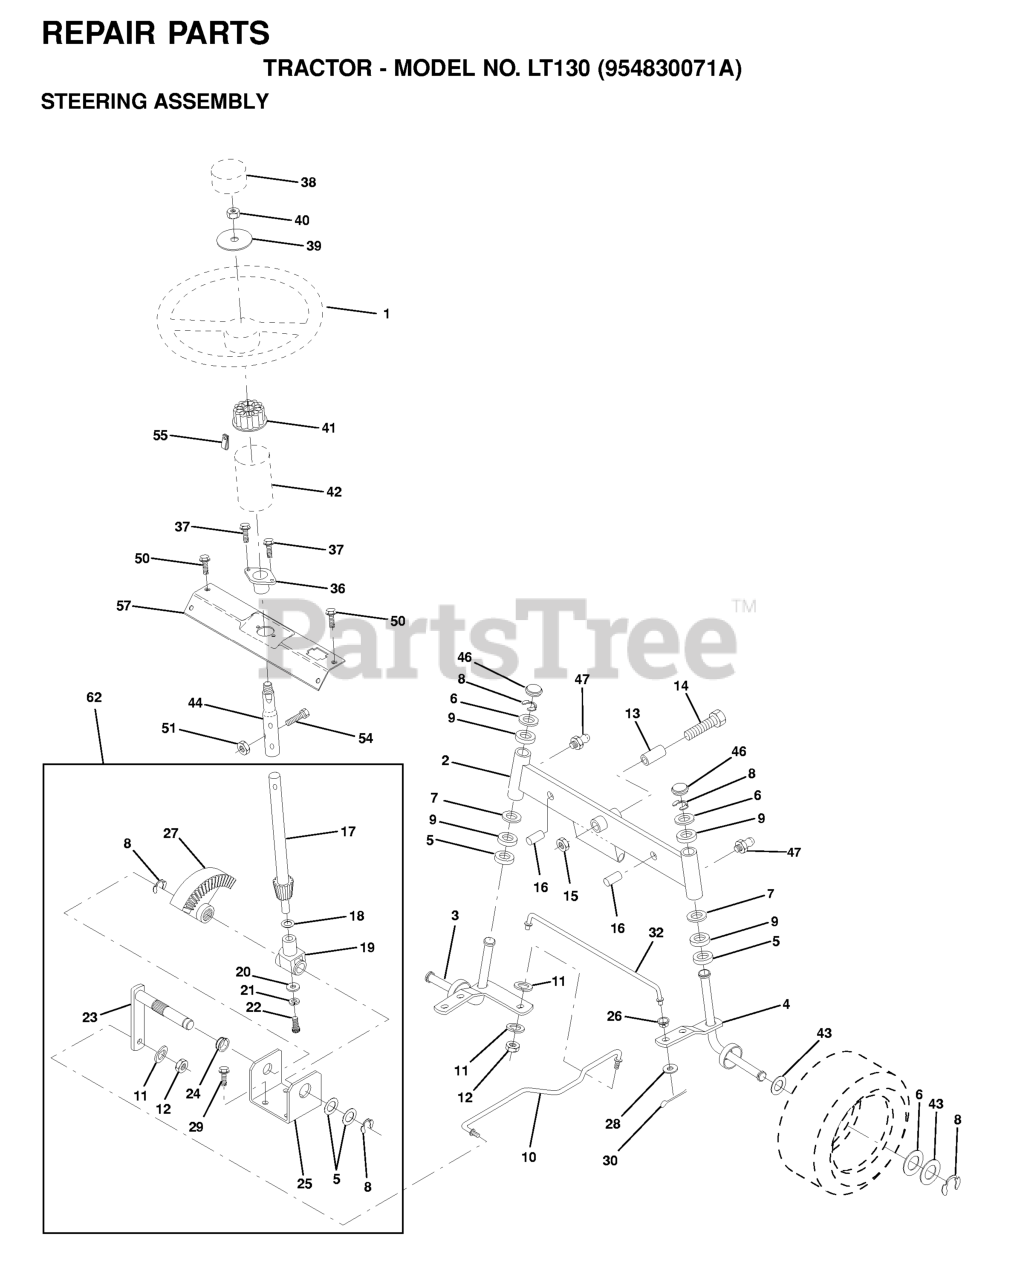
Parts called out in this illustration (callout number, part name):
1	STEERING WHEEL
3	SPINDLE LH
4	SPINDLE RH
5	THRUST WASHER
9	BRNG T
10	LINK.DRAG.SOL.BALL JT.20.064
11	WASHER, LOCK 3/8
12	NUT
13	BEARING
14	Bolt, Hex Head 5/8-11 x 3-1/2
15	NUT-LOC,FLANGE LT
17	SHAFT STEERING
18	THRUST WASHER
19	SHAFT,SUPPORT
20	WASHER
21	LOCKWASHER
22	SCREW,SPECIAL
23	SHAFT PITMAN
24	NYLINER T (7283A)
25	BRKT,STEERING
26	BUSHING LINK DRAG BLK LR
27	GEAR.SECTOR
28	WASHER
29	SCREW
30	COTTER PIN
32	TIE ROD
36	BUSHING-STRG LT
37	SCREW LT
38	INSERT,STR WHEEL
39	WASHER T
40	GRIPCO NUT
41	ADAPTER-WHEEL LT
42	BOOT, STEERING SHAFT
44	STEERING SHAFT
46	CAP.SPINDLE.BLACK
47	ZERK M
50	SCREW HEX CRT
51	NUT.71038.31-18.HEX.NYLOCK
54	BOLT.5/16-18X1-1/4 FULL.THREAD
57	SUPPORT STEERING SHAFT
62	KIT, STEERING ASSEMBLY
